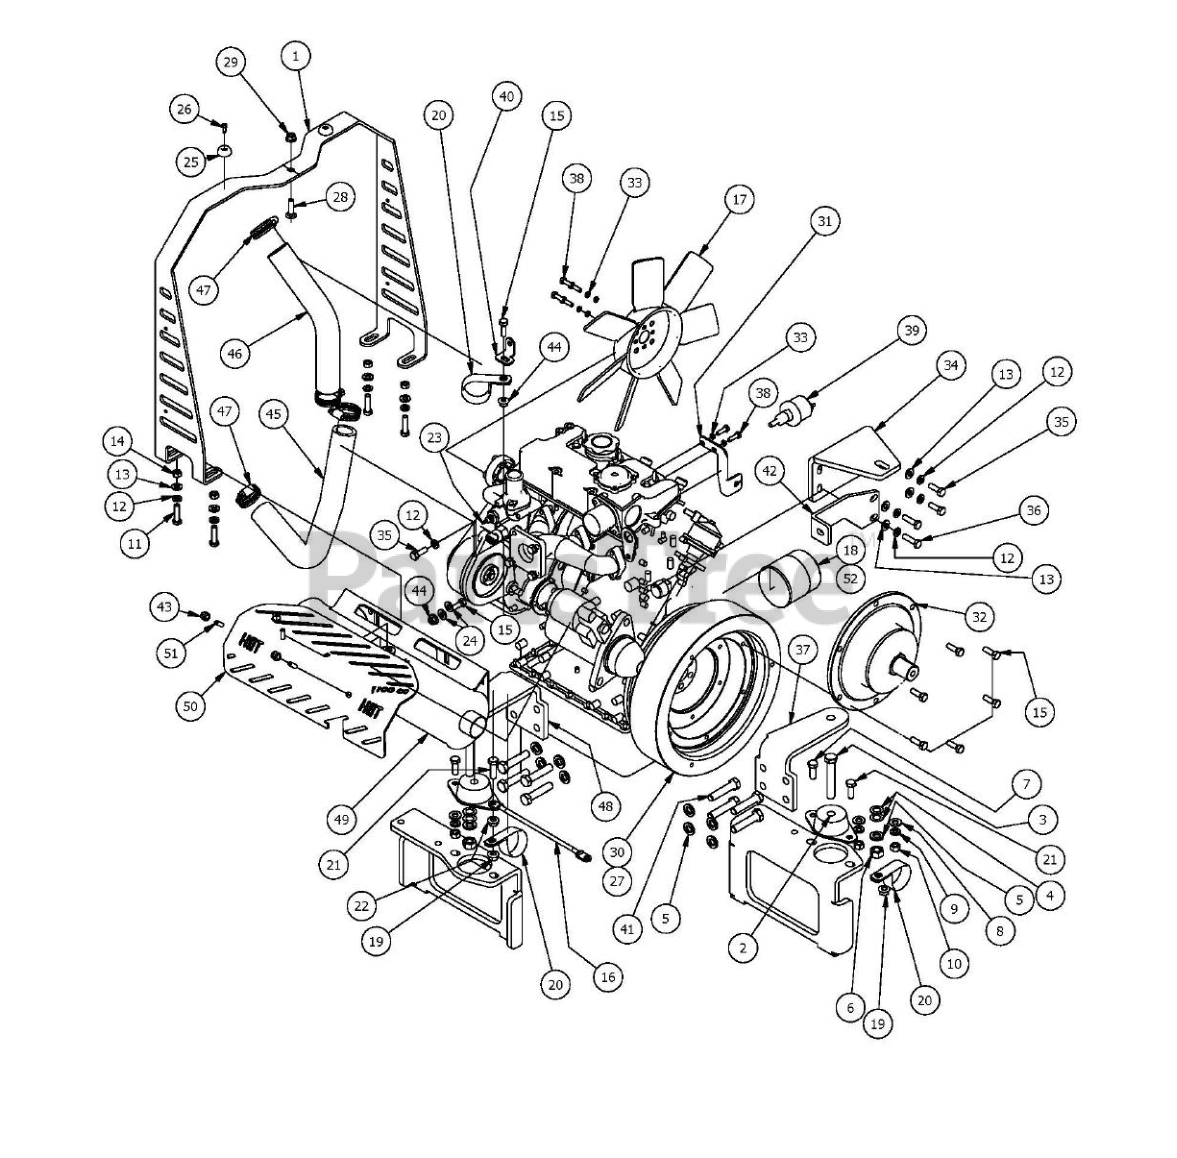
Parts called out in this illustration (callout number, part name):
1	Hood Holder Diesel
2	Rubber Isolator
3	1/2" x 3" Hex Bolt
4	1/2" Brass Washer
5	1/2" Lock Washer
6	1/2" Hex Nut
7	3/8" x 1" Hex Bolt
8	3/8" Flat Washer
9	3/8" Lock Washer
10	3/8" Hex Nut
11	5/16" x 1 1/4" Hex Bolt
12	5/16" Lock Washer
13	5/16" Flat Washer
15	5/16-18 x 1 Button Head Bolt
16	Starter to Chassis Cable - Diesel 1500cc
17	Engine Fan - Diesel
18	CAT Oil Filter
19	3/8 Nylock Jam Nut 1/2 Nut
20	Diesel Clamp 1 3/4" Vinyl
21	3/8" x 1 1/2" Hex Bolt
22	3/8" Flange Nut
23	Temperature Sender-2012 Gauge
24	1/4 USS Flat Washer Zinc
25	Button Bumper
26	# 10 x 1/2" Self Tapping Screw
27	1500cc Perkins Diesel Engine
28	5/16" x 1 1/4" Carriage Bolt
29	5/16" Nylon Flange Nut
30	1500cc CAT Diesel Engine
31	Diesel Throttle Bracket (4 Tier)
32	Stub Shaft
33	1/4" Lock Washer
34	Air Cleaner Support Diesel
35	M8 x 1.25 x 25mm Hex Head Bolt
36	M8 x 1.25 x 30mm Hex Head Bolt
37	Diesel Motor Side Support
38	6mm x 20mm Bolt
39	oil pressure guage sender
40	Diesel Radiator Hose Clamp Bracket
41	12mm Bolt- Diesel
42	Muffler Brace Diesel
43	1/4-20 Nylon Insert flange Nut
44	5/16" Flange Nut
45	Bottom Radiator Hose for Diesel
46	Top Radiator Hose for Diesel
47	1 1/8" Hose Clamp
48	Diesel Side Motor Mount (Left)
49	28/35hp Muffler
50	Diesel Muffler Guard (1500cc)
51	1/4" x 3/4" Set Screw
52	Perkins Oil Filter
